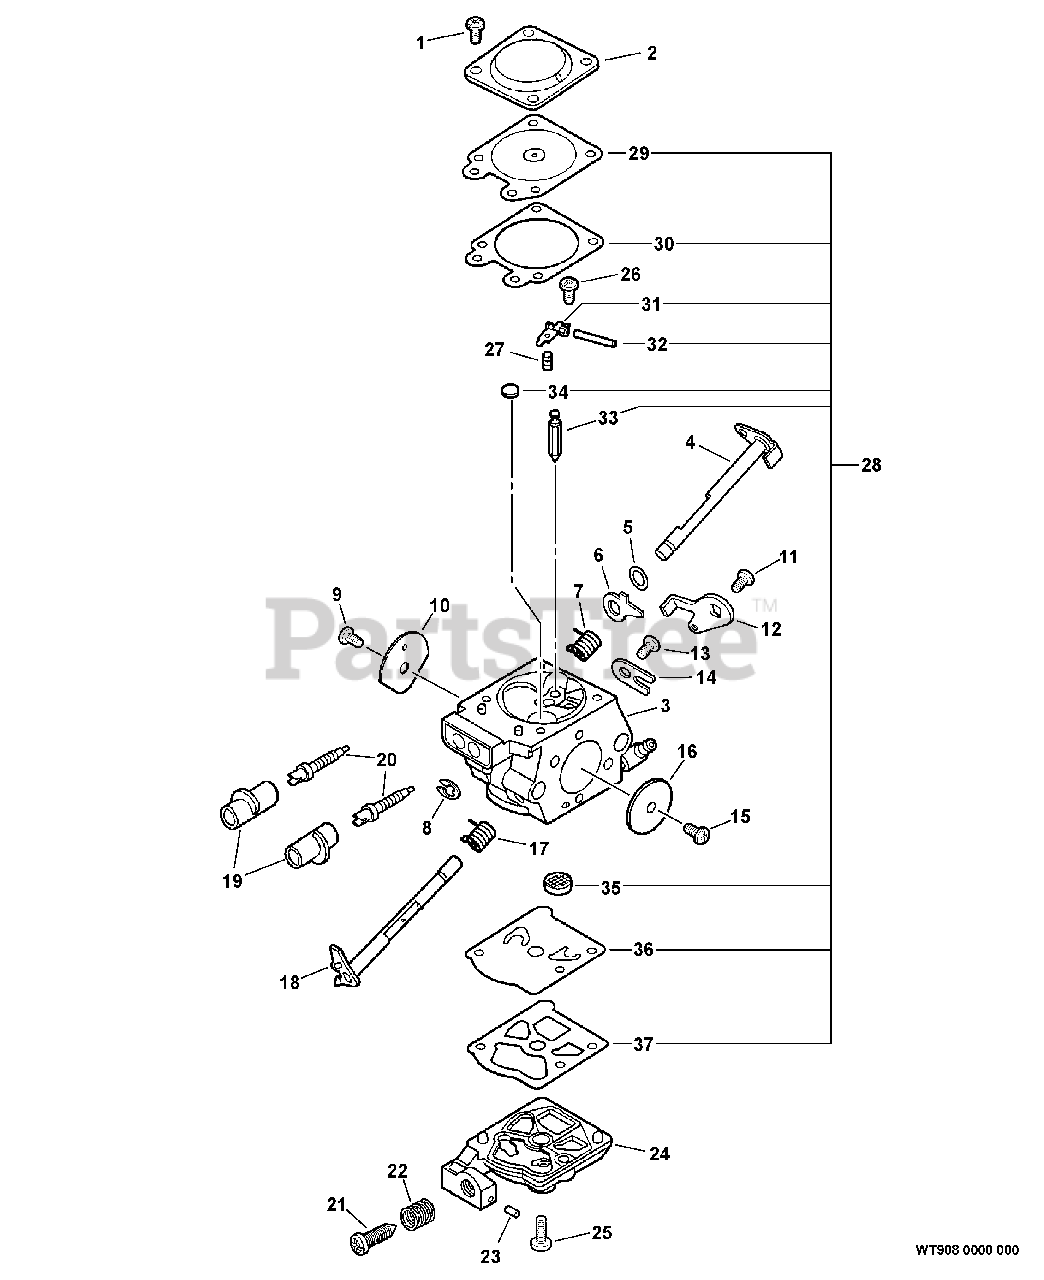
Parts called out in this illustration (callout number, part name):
2	COVER, METERING DIAPHRAGM
3	BODY, CARBURETOR
4	SHAFT, CHOKE
6	LEVER, FAST IDLE
7	SPRING, CHOKE RETURN
10	VALVE, CHOKE
12	LEVER, THROTTLE
14	CLIP, THROTTLE SHAFT
16	VALVE, THROTTLE
17	SPRING, THROTTLE RETURN
18	SHAFT ASSY, THROTTLE
19	CAP, LIMITER
20	NEEDLE, MIXTURE
21	SCREW, IDLE ADJUST
22	SPRING, IDLE ADJUST
23	PLUG, FRICTION
24	COVER, FUEL PUMP
26	SCREW, METERING LEVER PIN
27	SPRING, METERING LEVER
28	REPAIR KIT
29	DIAPHRAGM, METERING
30	GASKET, DIAPHRAGM
31	LEVER, METERING
32	PIN, METERING LEVER
33	VALVE, INLET NEEDLE
34	PLUG, WELCH
35	STRAINER
36	DIAPHRAGM, PUMP
37	GASKET, PUMP
